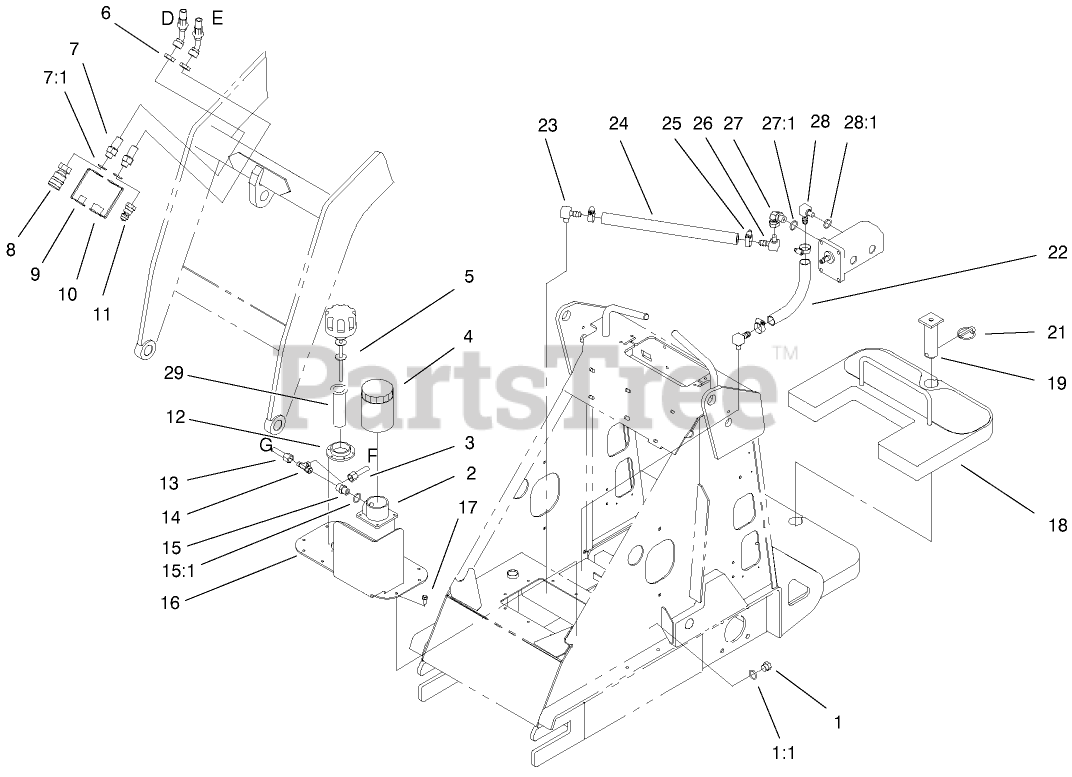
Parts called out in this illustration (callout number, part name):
1	PLUG-HEX
1:1	O-RING
2	FILTER-MOUNT
3	TUBE-HYD
4	FILTER-ELEMENT
5	CAP-HYD
6	NUT-BULKHEAD
7	UNION-BULKHEAD
7:1	O-RING
8	QUICK COUPLER-FEMALE
9	Dust Plug
10	Cap-Dust
11	QUICK COUPLER - MALE
12	Cap-Mount
13	TUBE-HYD
14	FITTING-TEE
15	FITTING-STRAIGHT
15:1	O-RING
16	COVER-TANK, TOP
17	SCREW-HH
18	COUNTERWEIGHT ASM
21	PIN-LYNCH
22	HOSE-SUCTION
23	FITTING-BARBED 90 DEG
24	HOSE-SUCTION
25	CLAMP-HOSE
26	FITTING-BARBED 90 DEG
27	FITTING
27:1	O-RING
28	FITTING-BARBED 90 DEG
28:1	O-RING
29	FILTER-SCREEN
